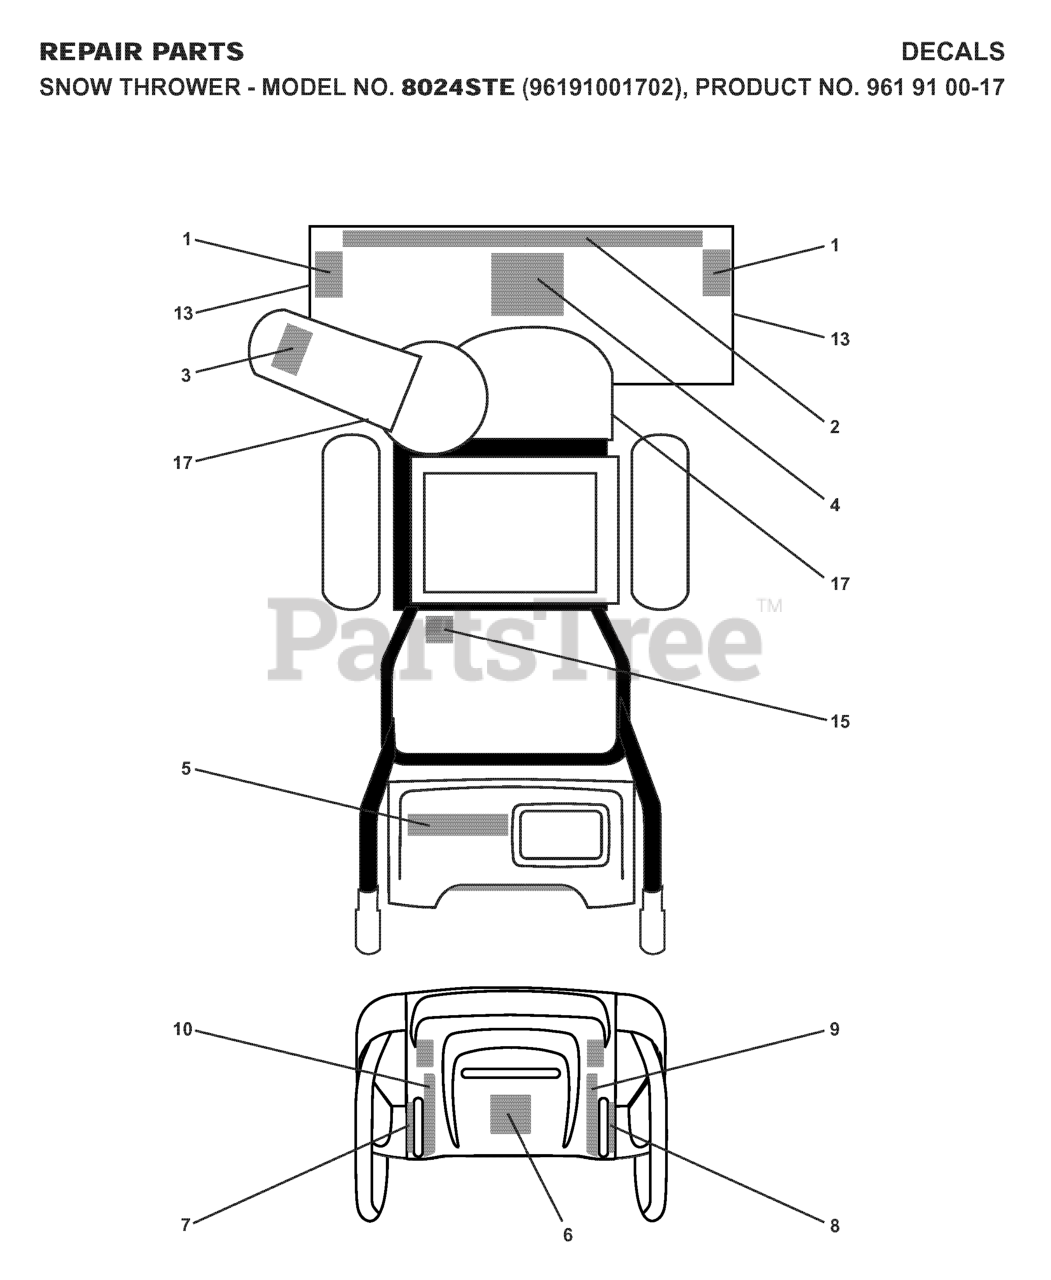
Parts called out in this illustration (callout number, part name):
1	DECAL.AUGER.SAFETY.
3	DECAL.CHUTE.SAFETY.
4	DECAL.AUGER."
6	DECAL.CONSOLE.INSTRUCTION
10	DECAL.REM.DEFLECTOR.LT
13	DECAL, HUSQVARNA
15	DECAL.FENDER
17	DECAL.BELT.GUARD.
